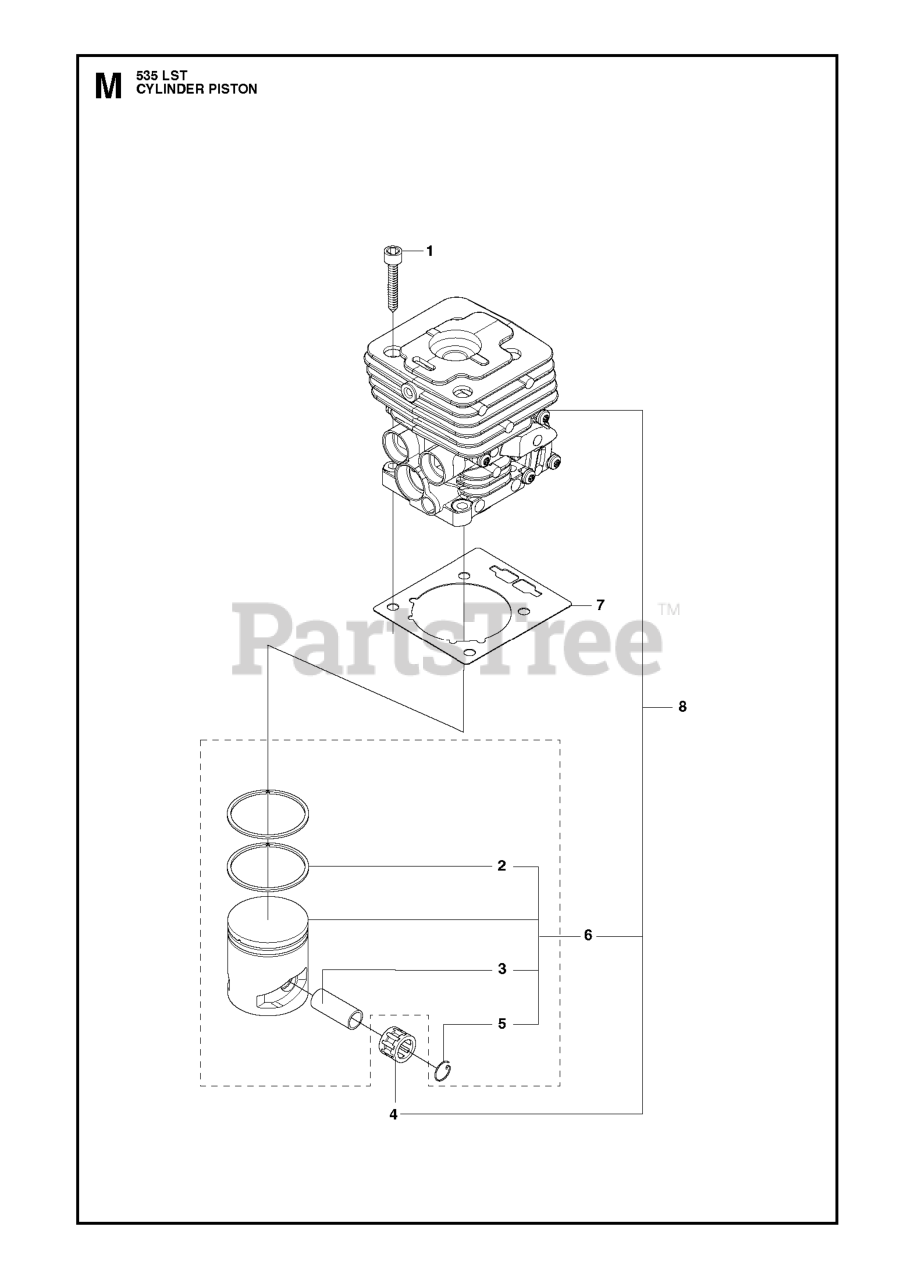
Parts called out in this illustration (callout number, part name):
1	SCREW MC6S 5X25
2	PISTON RING
3	PISTON PIN 22X10X6,5 GCR15
4	SUPPORT BUSHING
5	LOCKING RING
6	PISTON ASSY
7	GASKET CYLINDER
8	CYLINDER ASSY
